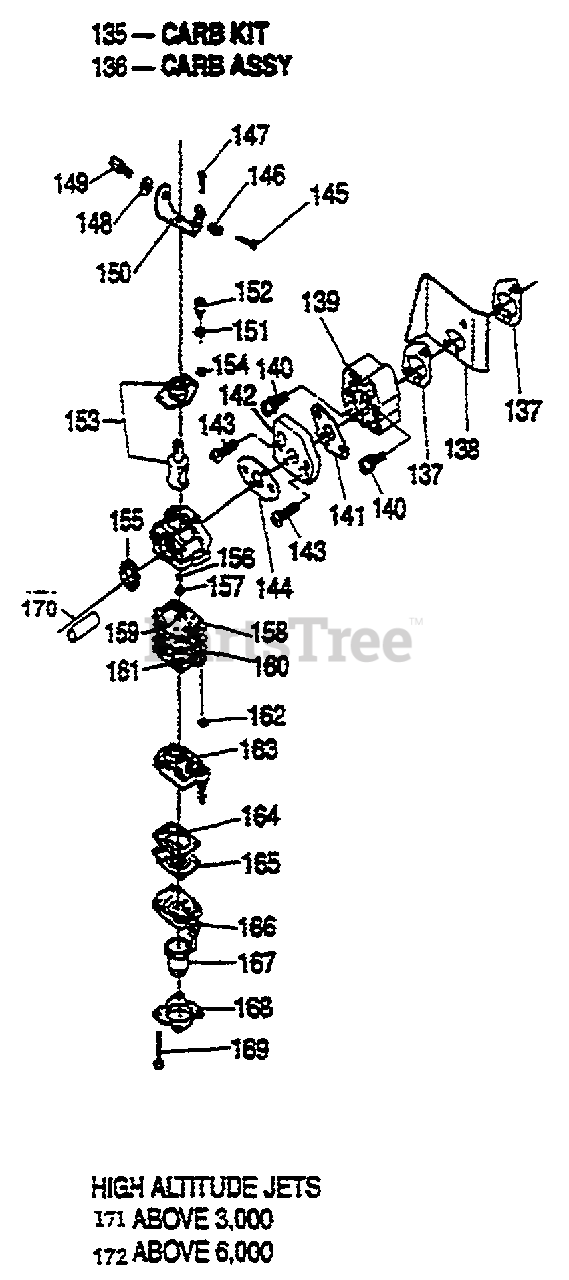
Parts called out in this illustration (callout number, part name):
135	CARB. KIT
136	CARB. ASSY
137	GASKET, INSULATOR
139	INSULATOR
140	SCREW & WASHER
141	GASKET, CARB.
144	GASKET, CARB.
145	SCREW, IDLE
146	SPRING, IDLE
148	NUT. CABLE ADJ.
149	ADJUSTER CABLE
153	VALVE, THROTTLE
154	RING, SWIVEL
158	GASKET, PUMP
159	DIAPHRAGM
162	SCREEN, INLET
163	BODY ASSY.
164	GASKET, DIAPH.
165	DIAPHRAGM
166	BODY, PUMP
167	PUMP, PRIMER
168	COVER, PRIMER
169	SCREW, COVER
171	JET HIGH ALT.
172	JET HIGH ALT.
